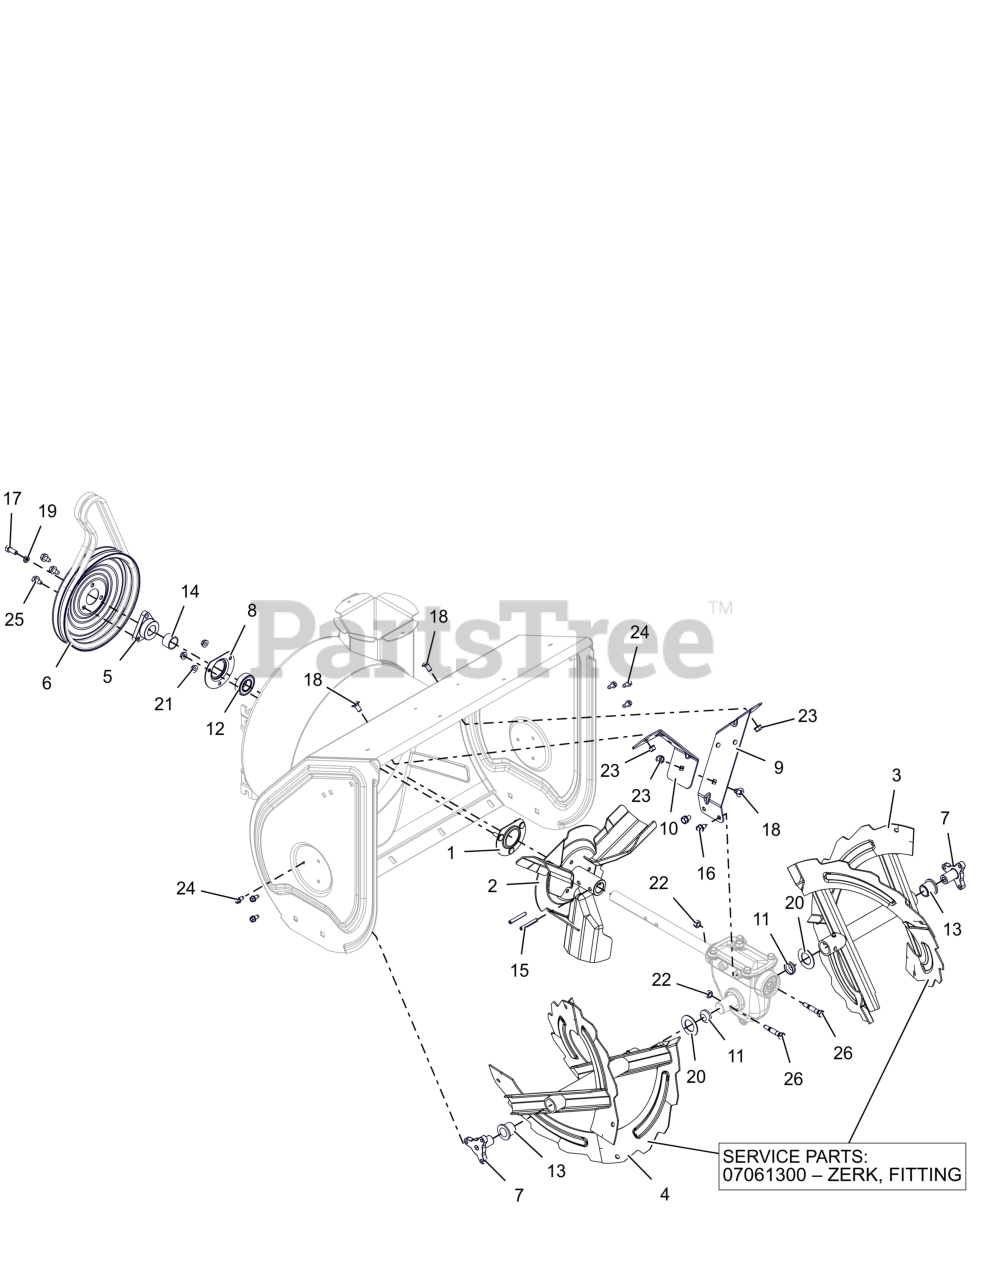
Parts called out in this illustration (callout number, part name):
1	BEARING FLANGE
2	IMPELLER, 3 BLADE-14"
3	RAKE, LH W/ZERK - 24"
4	RAKE, RH W/ZERK - 24"
5	PULLEY HUB, D-BORE .87 PRO
6	PULLEY, SPIN FORM DUAL GROOVE
7	SUPPORT, RAKE BUSHING
8	BEARING FLANGE
9	BRACKET, GEARCASE SUPPORT - LH
10	BRACKET, GEARCASE SUPPORT - RH
11	PLUG, RAKE TUBE
12	BRG-BALL .876 X 1.750 X .50
13	BSHG-FLG, NY.778 ID X 1.018 OD
14	BSHG,SPCR .895X1.065X.693
15	PIN-ROLL .250X1.75
16	BLT, SEMS .31-18X.50 G5 ZCC
17	BLT, HEX .31-24X.750 G5 ZCC
18	BLT,RHSSN.31-18X.625 G5 ZCCP30
19	WSHR, LK-HVY .312X.097 ZCC
20	WSHR- FLT 1.010X1.755X.062 ZCC
21	NUT-LK-CTR-FLG .25-20 ZC120
22	NUT,LK-CTR .31-18 GA ZCC
23	NUT-LK-TOP-FLG .312-18 GF ZCC
24	SCR-TAP .25-20X.50 HWH ZCC
25	SCR,TAP .312-18X.50 HWH TR ZCC
26	SHEAR BOLT SERVICE ASSEMBLY (INCLUDES NUT)
